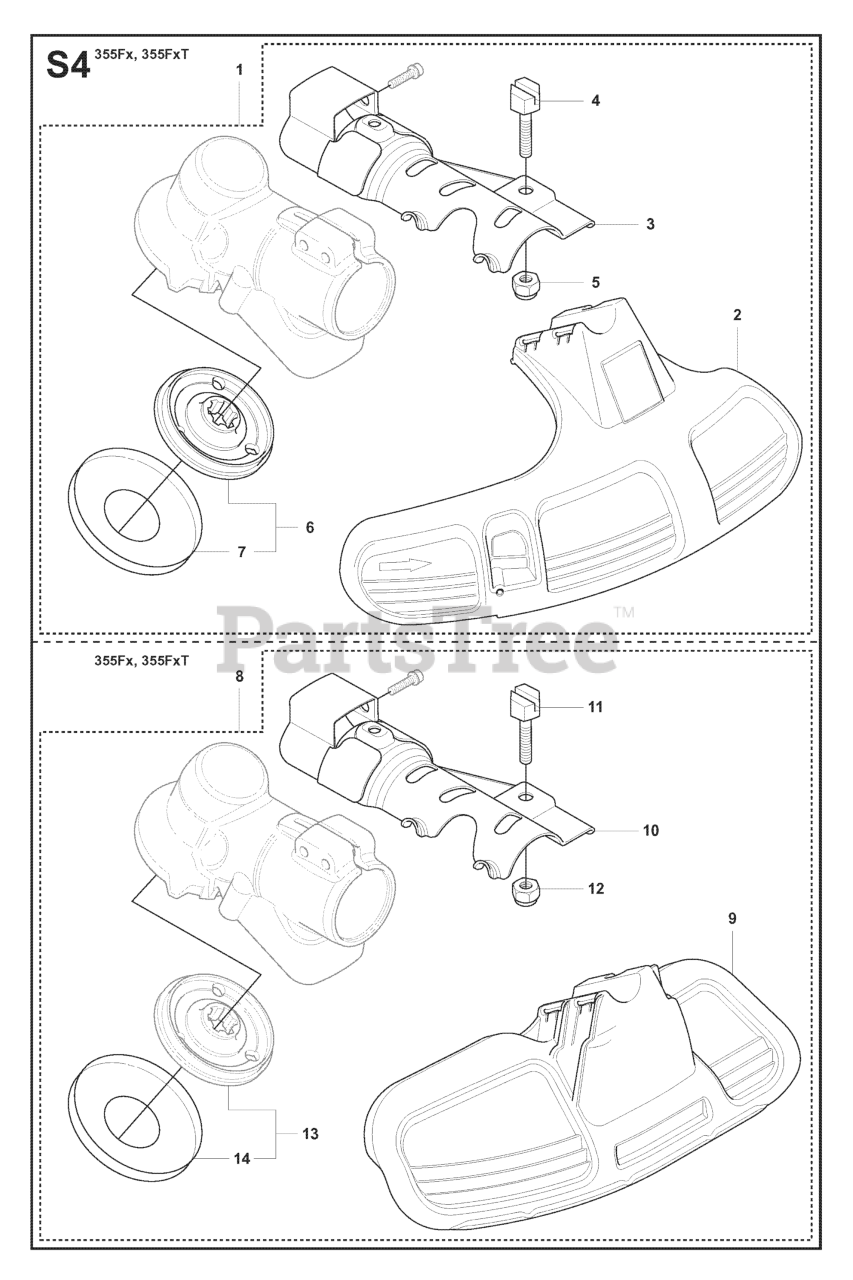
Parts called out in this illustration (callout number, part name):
1	GUARD ASSY
2	PROTECTION
3	ATTACHMENT PLATE
5	LOCKNUT M6
6	RP CARRIER
7	GRASS SEALING
8	GRASS BLADE GUARD ADAPTER INCL
9	BLADE GUARD GRASS
10	ATTACHMENT PLATE
12	LOCKNUT M6
13	RP CARRIER
14	GRASS SEALING
